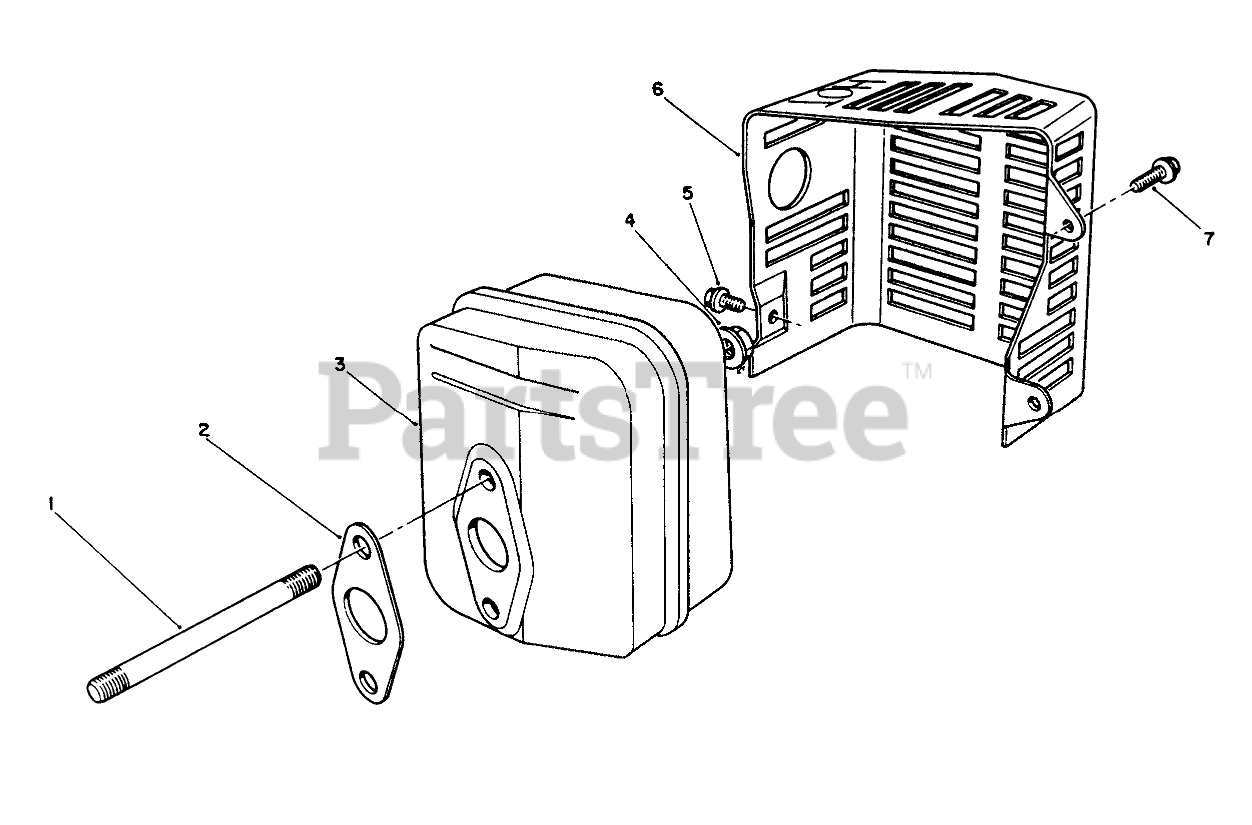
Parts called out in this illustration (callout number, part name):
2	GASKET
3	MUFFLER
5	SCREW
6	COVER
